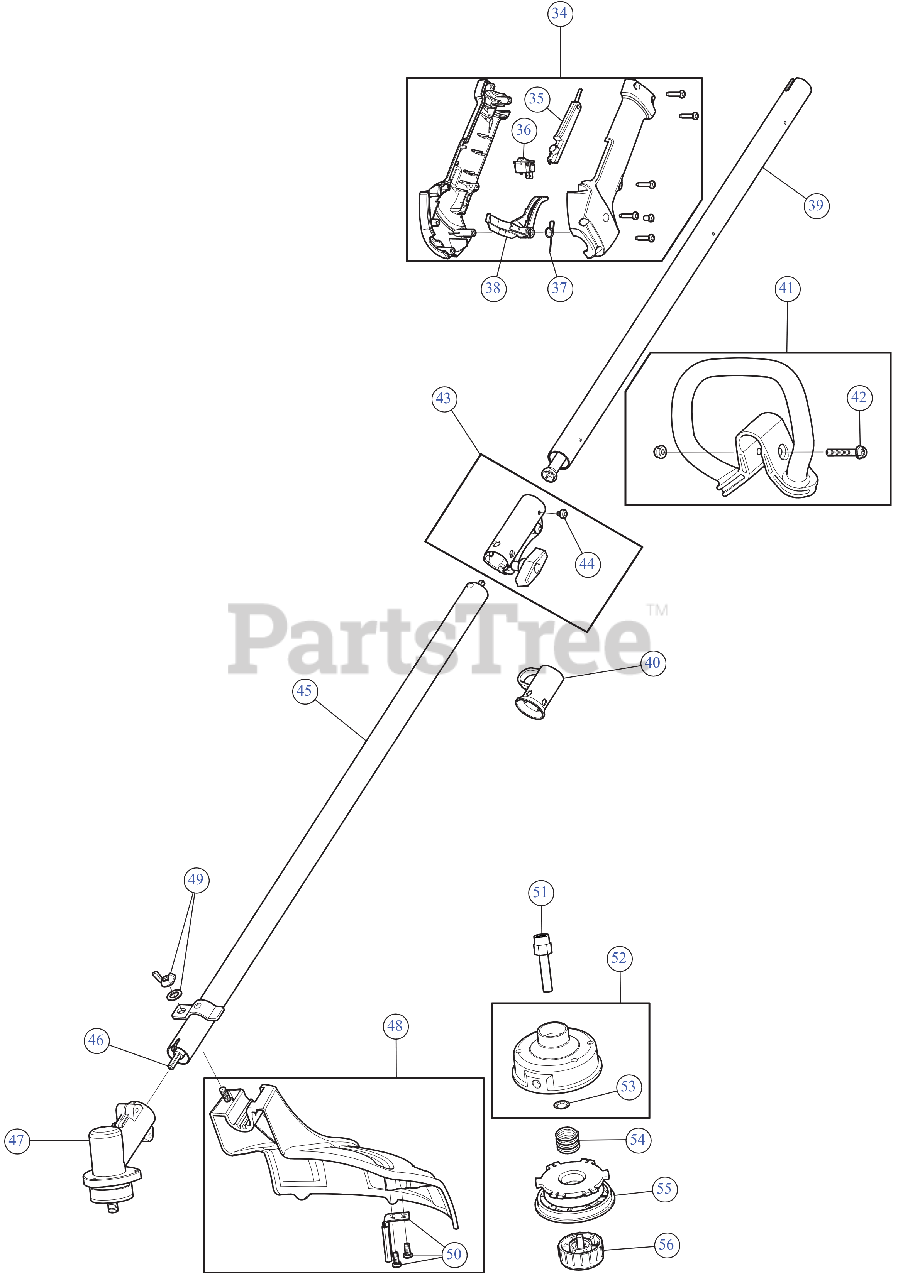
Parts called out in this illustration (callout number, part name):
34	THROTTLE GRIP ASSEMBLY
35	LEVER LOCK OUT
36	SW, MOMENTARY ON/O
37	SPRING TRIG
38	THROTTLE TRIGGER
39	BOOM ASSEMBLY UPR
40	HANGER
41	D-HANDLE
42	BOLT 1/4-20X1 1/2
43	COUPLER ASSEMBLY
44	SCREW, 10-32X.250 TA
45	LOWER BOOM ASSEMBLY
46	LOWERIBLE DRIVE SHAFT
47	GEARBOX ASSEMBLY 1PC
48	GUARD/BLADE ASM
49	BLADE GUARD MOUNTING HARDWARE
50	BLADE ASSEMBLY W/HDW
51	SHAFT ADAPTER
52	REEL:OTR W/RET
53	RETAINER .625 OD 2
54	SPRING-SPOOL
55	INNER REEL
56	BUMP KNOB (BLACK)
